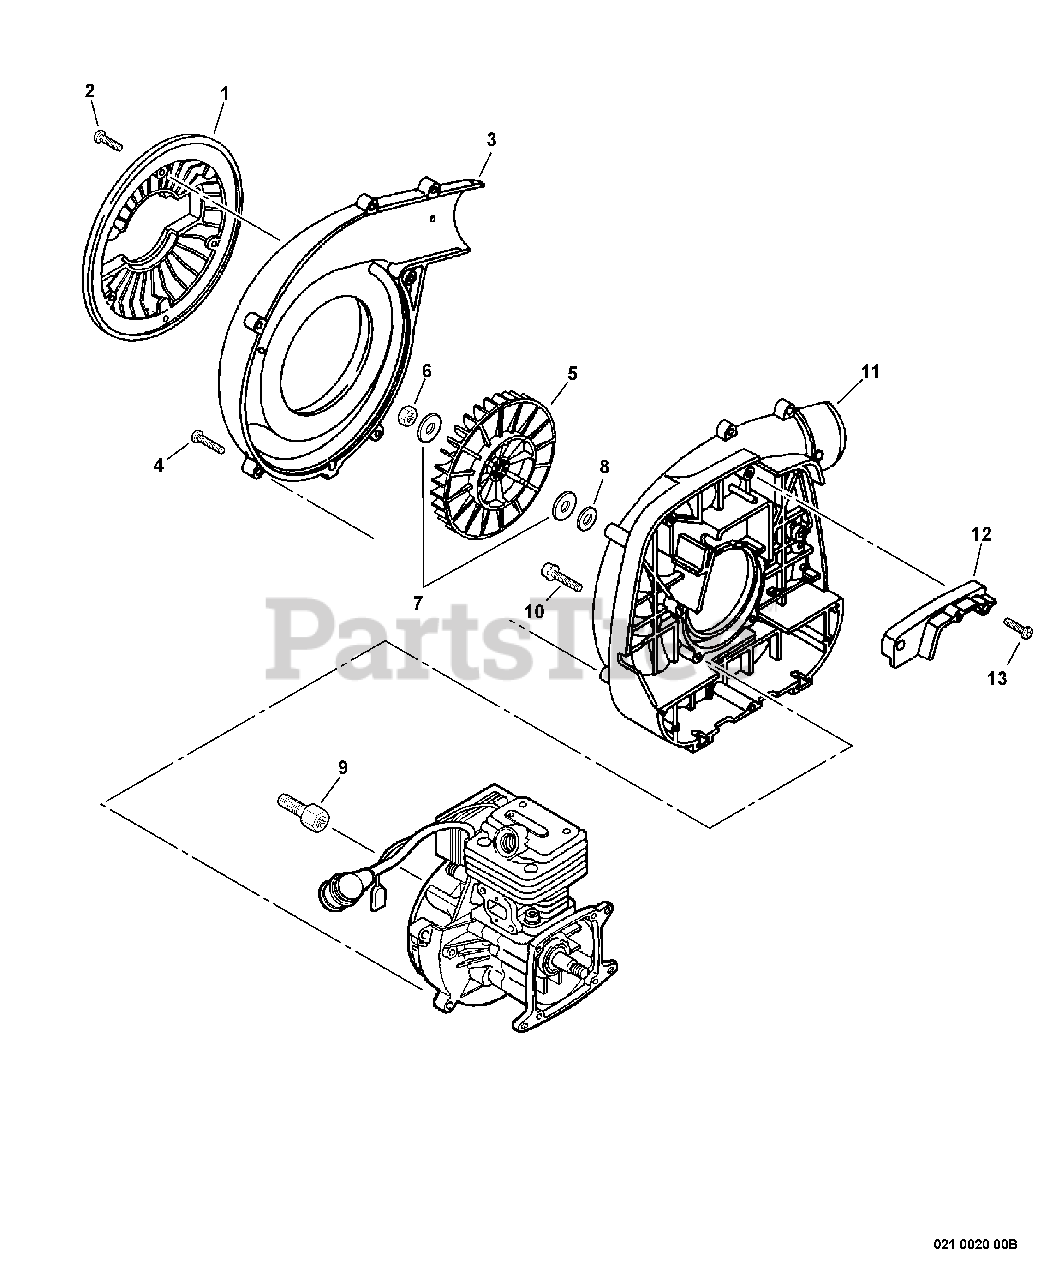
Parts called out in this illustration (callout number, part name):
1	GUARD, DEBRIS
2	SCREW - 5X16 -- TAPPING
3	COVER, FAN - OUTER
4	SCREW - 5X20 -- TAPPING
7	WASHER - 8
8	WASHER
9	HUB, FAN
10	SCREW - 5X20
11	COVER, FAN - INNER
12	COVER, FAN CASE
13	SCREW - 5X16 -- TAPPING
